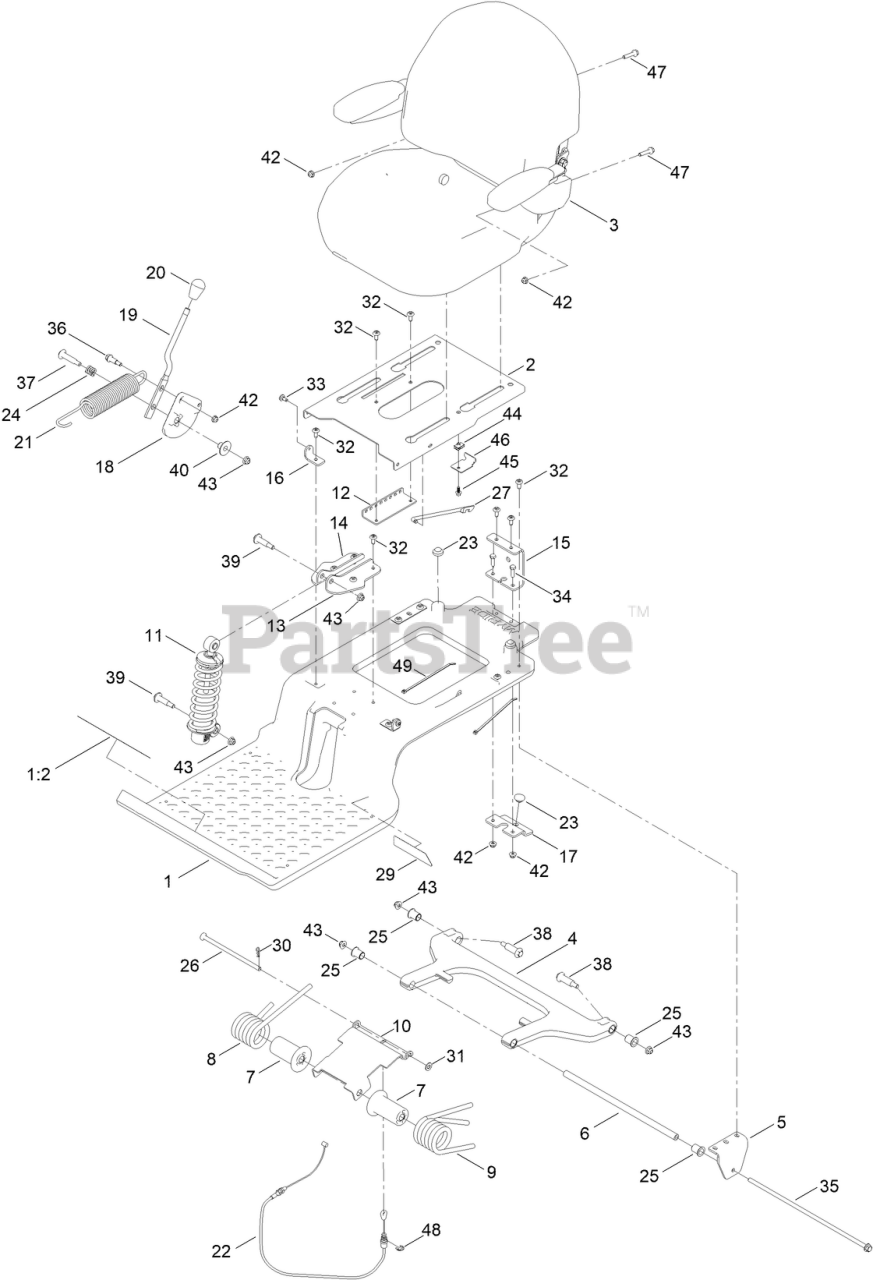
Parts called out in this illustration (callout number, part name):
1	SUBFRAME ASM
1:2	DECAL-DANGER
2	PAN-SEAT
3	SEAT ASM
4	ARM, SWING
5	BRACKET-MOUNT, SWING ARM
6	TUBE-SPACER
7	RETAINER-SPRING
8	SPRING-TORSION, RH
9	SPRING-TORSION, LH
10	PLATE-ADJUSTER
11	SHOCK/SPRING ASM
12	BRACKET-LATCH, SEAT
13	BRACKET-SHOCK MOUNT, UPPER (LH)
14	BRACKET-SHOCK MOUNT, UPPER (RH)
15	BRACKET-CABLE
16	BRACKET-SEAT
17	BRACKET LOWER
18	PULLEY - CAM
19	LEVER - ADJUSTMENT
20	KNOB-MR
21	SPRING-EXTENSION
22	CABLE-ADJUSTMENT, MYRIDE
23	BUMPER-SEAT
24	SPRING-COMPRESSION
25	BUSHING-FLANGE
26	ROD-ADJUSTMENT
27	ROD-PROP, SEAT
29	DECAL-MYRIDE
30	PIN-HAIR
31	WASHER-FLAT
33	SCREW-SHOULDER
34	SCREW-HH
35	SCREW-HHF
36	BOLT-SHOULDER, HHF
37	BOLT-SHOULDER
38	BOLT-SHOULDER
39	BOLT-SHOULDER
40	BUSHING - FLANGE
42	NUT-HF
43	NUT-HF, NI
45	SCREW-HHF
46	BRACKET-STOP, SEAT
47	SCREW-HHF
48	RING-RETAINING, EXTERNAL
49	TIE-CABLE
